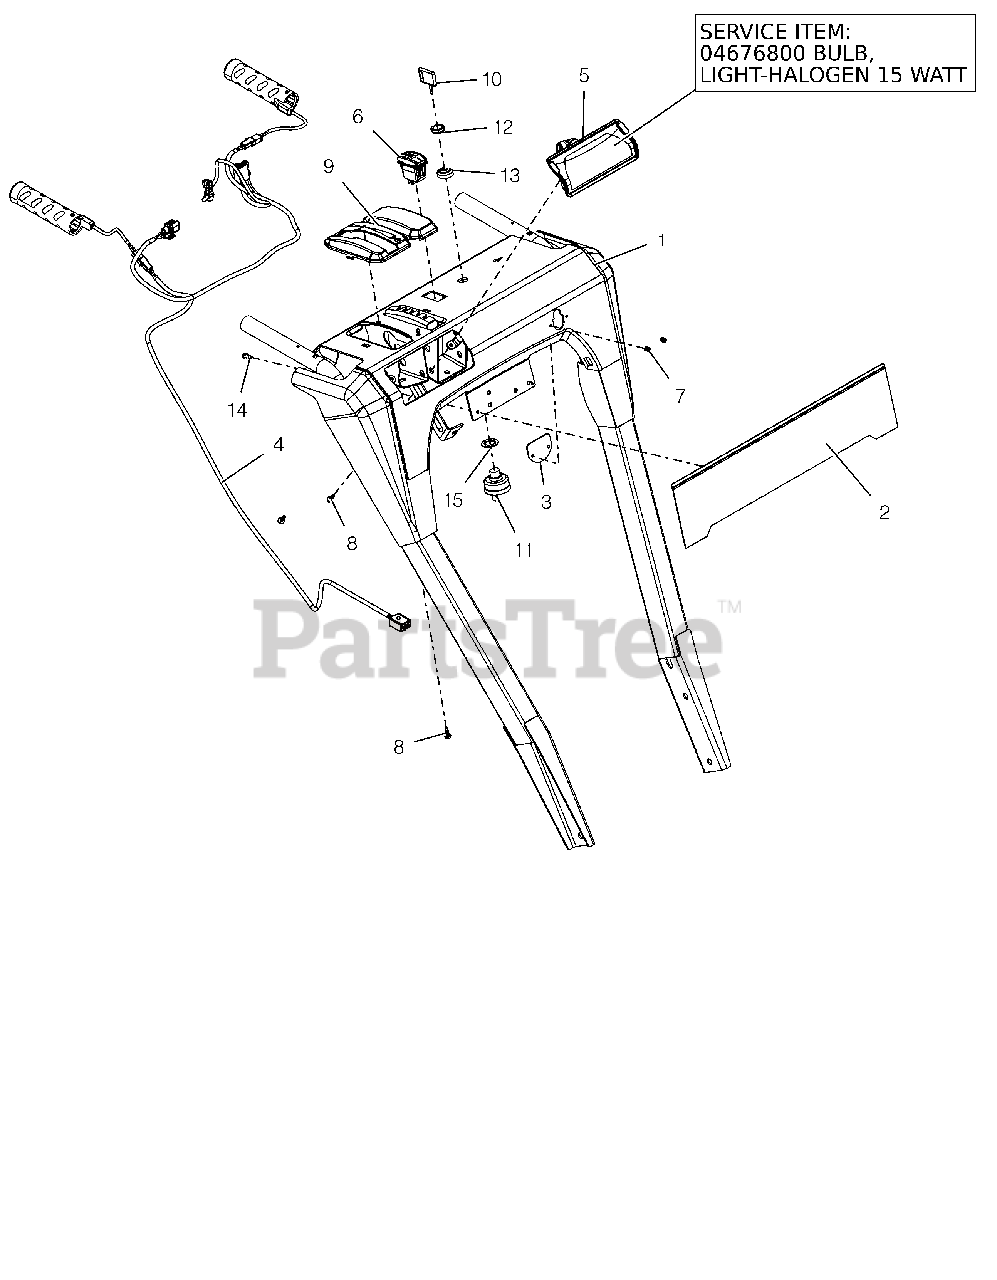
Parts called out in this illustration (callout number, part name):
1	PANEL, DASH - W/CTR DECAL(12V)
2	WLDMT, BRAND PLATE
3	COVER, DASH BRKT, BRUSH
4	HARNESS,ELEC - HANDLEBAR 12V
5	HEADLIGHT ASY, HOLO 15W 2 SHOT
5	BULB, LIGHT-HALOGEN 15 WATT
6	SWITCH,ROCKER SPST-ON/OFF
7	RVT-POP #43 .125X.313 STL ZINC
8	SCR-TAP #10X.50 BOSS INDHXHD
9	BEZEL, SHIFT - HYDRO BRUSH
10	KEY -W/CAP
11	IGNITION SWITCH ASSEMBLY
12	NUT-PANEL .625-32 GRECO
13	CAP - IGNITION SWITCH
14	@SCR-TAP 10-24X.50 HWH TR YWZC
15	WSHR-LK-INT .625X.045 YWZC
